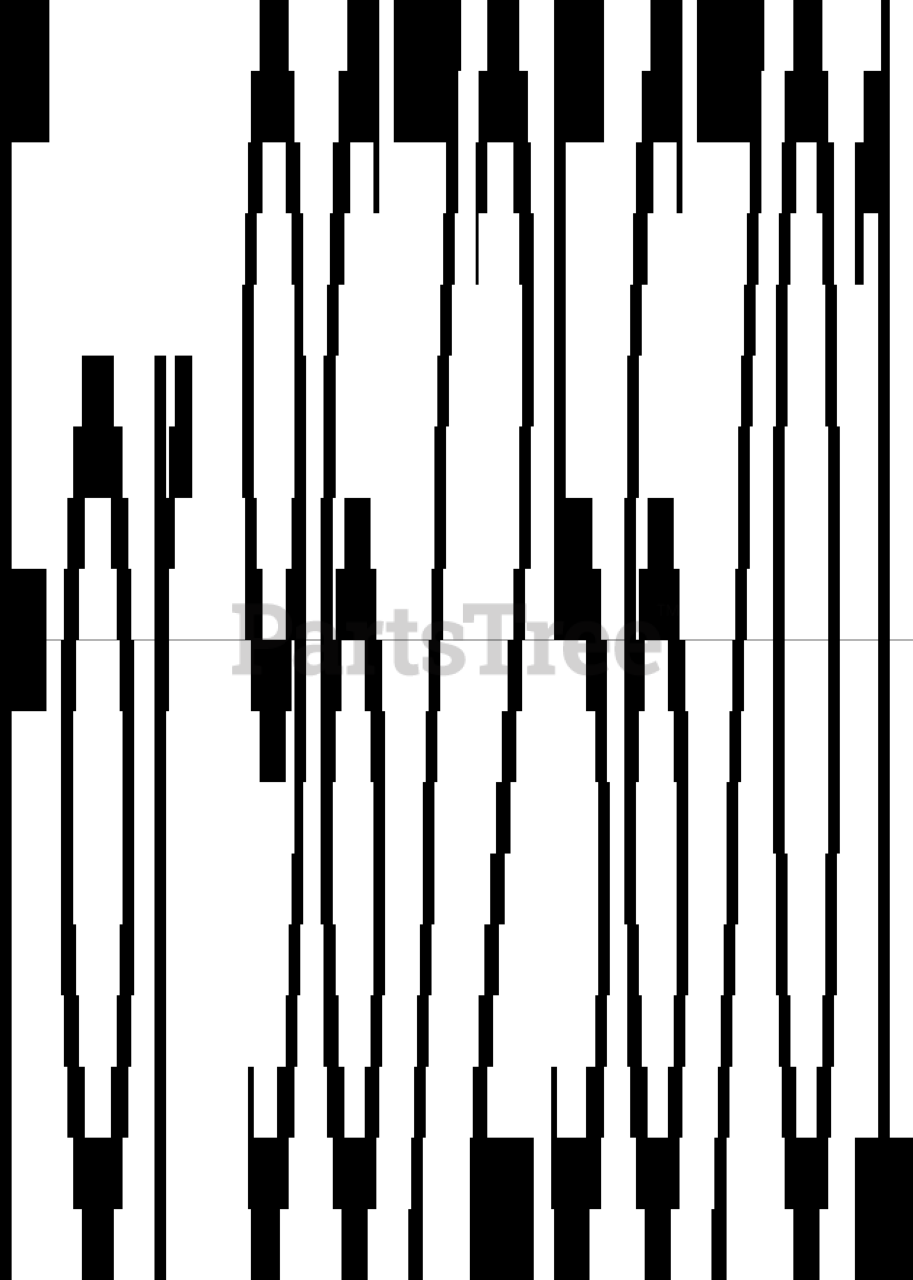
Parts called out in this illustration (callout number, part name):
11	NUT
16	RETAINING RING SGA 8
49	LABEL, DANGER
